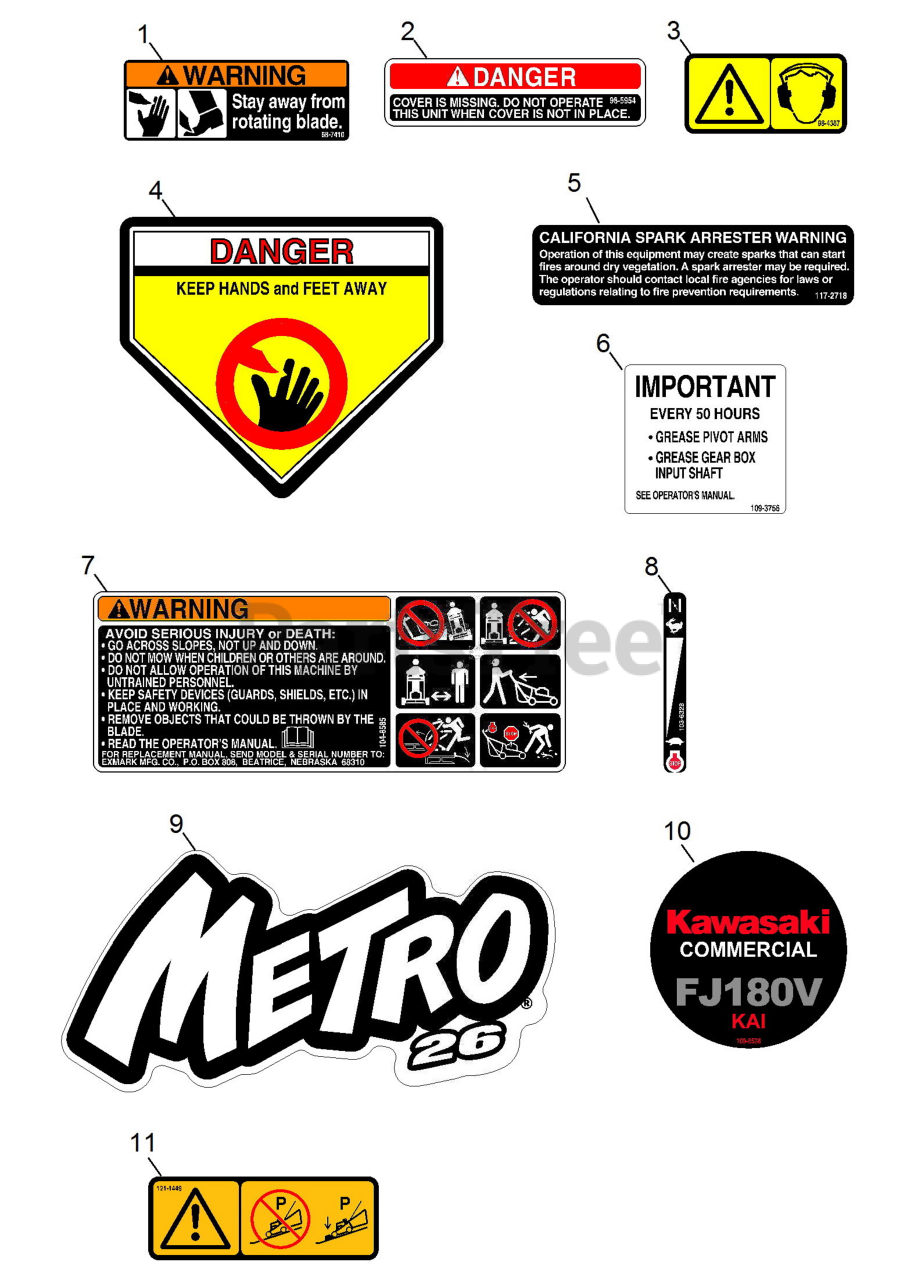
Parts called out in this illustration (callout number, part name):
1	DECAL-BLADE
2	DECAL-COVER, MISSING
3	DECAL-PROTECTION, EAR
4	DECAL-DANGER
5	DECAL-ARRESTER, SPARK
6	DECAL,SERVICE M26
7	DECAL-WARNING
8	DECAL-THROTTLE / CHOKE
9	DECAL,METRO 26
11	DECAL-WARNING, BLOCK
